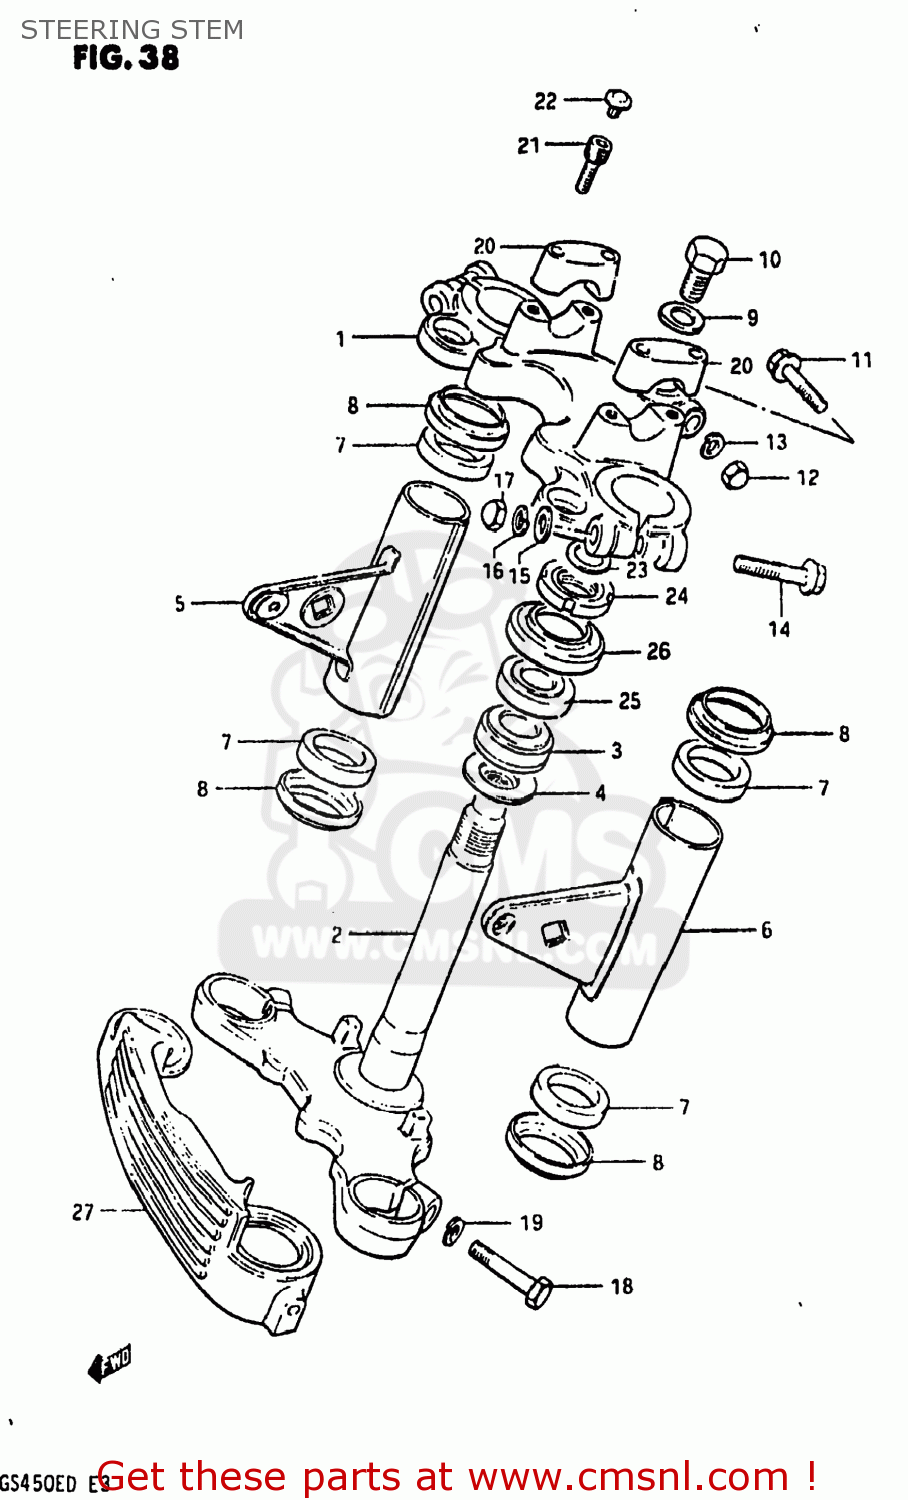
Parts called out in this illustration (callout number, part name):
1	HEAD,STEERING STEM
2	STEM,STEERING
3	BEARING
4	WASHER,THRUST
5	BRACKET,HEADLAMP,RIGHT
6	BRACKET,HEADLAMP,LEFT
7	CUSHION,HEADLAMP BRACKET
8	CAP,HEADLAMP BRACKET
9	WASHER
10	BOLT(12X20)
11	BOLT
12	NUT
13	LOCK WASHER
14	BOLT 10X55
15	WASHER
16	LOCK WASHER
17	NUT
18	BOLT 10X40
19	LOCK WASHER
20	HOLDER,HANDLEBAR(BLACK)
21	BOLT
22	CAP(OD:14.5)
23	WASHER(18.5X24X1)
24	NUT,STEERING STEM
25	TAPER,ROLLER BEARING
26	DUST SEAL,STEERING UPR
27	COVER,FRONT FORK
